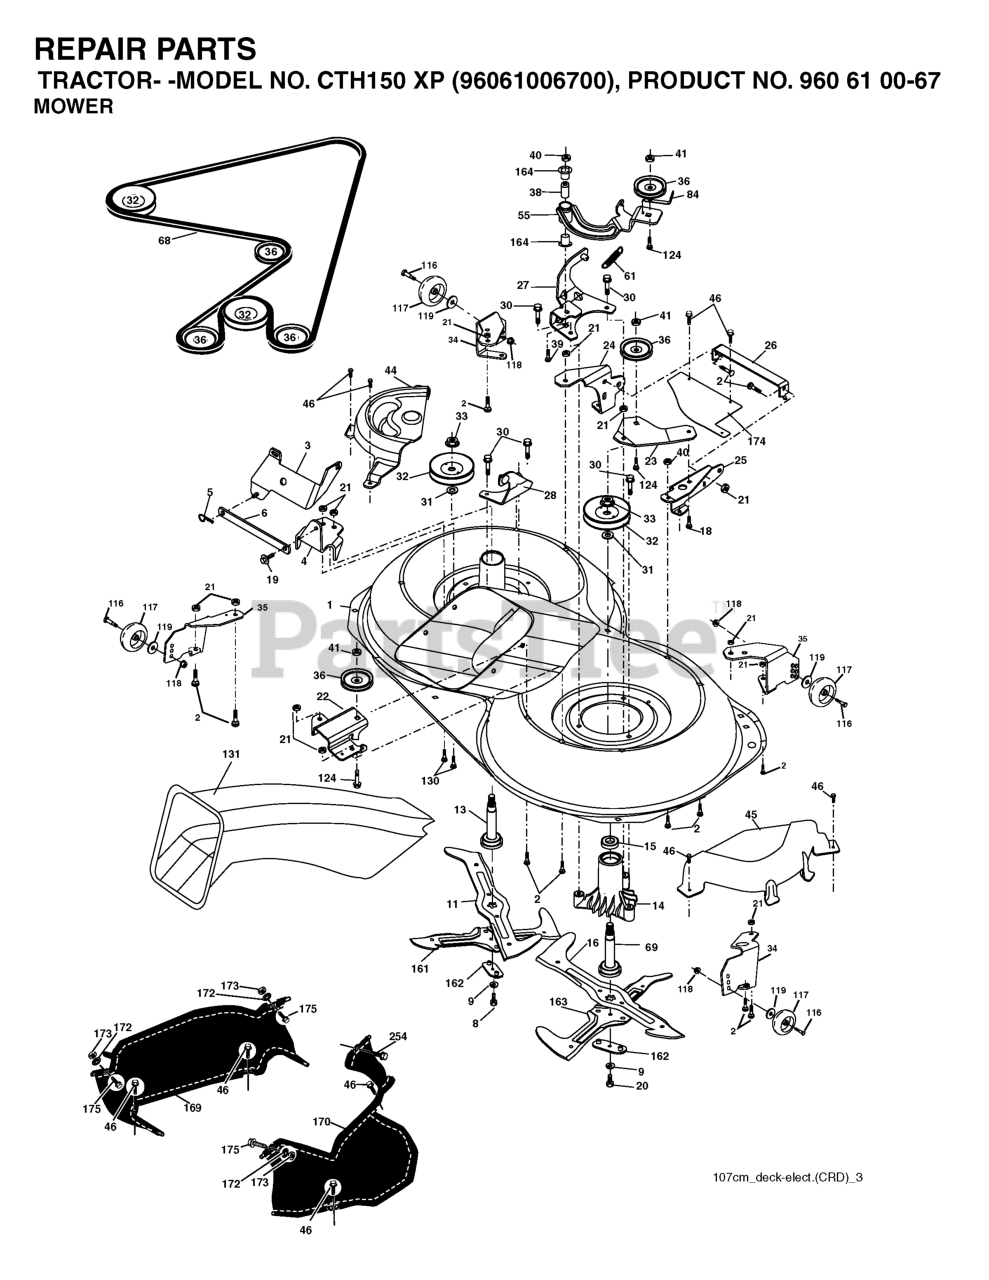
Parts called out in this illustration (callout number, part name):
1	Housing Asm. Mower 107 CRD
2	RP BOLT 5/16-18 X3/4 ZN/YEL GR
5	RETAINER-SPRNG RB
6	BAR.SWAY.92.CRD
8	BOLT.3/8-24X1.25 GR8
9	LOCKWASHER
11	BLADE.3N1.LH.CRD
13	SHAFT ASM VENT
14	HOUSING.MANDREL.VENTED (MACHD)
16	BLADE.3N1.RH.CRD
19	BOLT SHD 5/16-18
20	BOLT.3/8-24X1.25GR8. LHTHRD
21	LOCKNUT
22	BRACKET.IDLER.RR.107.CRD
25	BRACKET RF
26	SUPPORT
28	BRACKET
30	SCREW, WASHER HEAD
31	WASHER.SPACER.MANDREL
32	PULLEY.MANDREL.4.80 PD.2006
33	NUT.FLANGE.LOCK.TOP
34	BRACKET
35	BRACKET
36	PULLEY.IDLER.4.25
41	NUT LOCK FLG 3/8-16 UNC
45	COVER.MANDREL.RH.CRD
46	SCREW.1/4-20X5/8
55	ARM.IDLER.107.CRD
61	SPRING
68	HEX-BELT 107 MOWER
69	SHAFT.ASM.W/LWR.BRG.RH.THREAD
84	KEEPER, BELT IDLER
116	SHOULDER BOLT
117	RP WHEEL. GUAGE RALLY
118	LOCKNUT
119	WASHER.5/16.FLAT.STE.STD.
124	BOLT.3/8-16X1.50
130	BOLT.CARR.SQNK.5/16-18UNC.X3/4
131	CHUTE BAGGER
163	BLADE.CROSS.RH.CRD.107
164	BRNG T
172	PUSH.NUT.ROUND.3/8.DIAM
173	NUT
174	PLATE
175	BOLT D
254	SCREW 3/8-16X1
